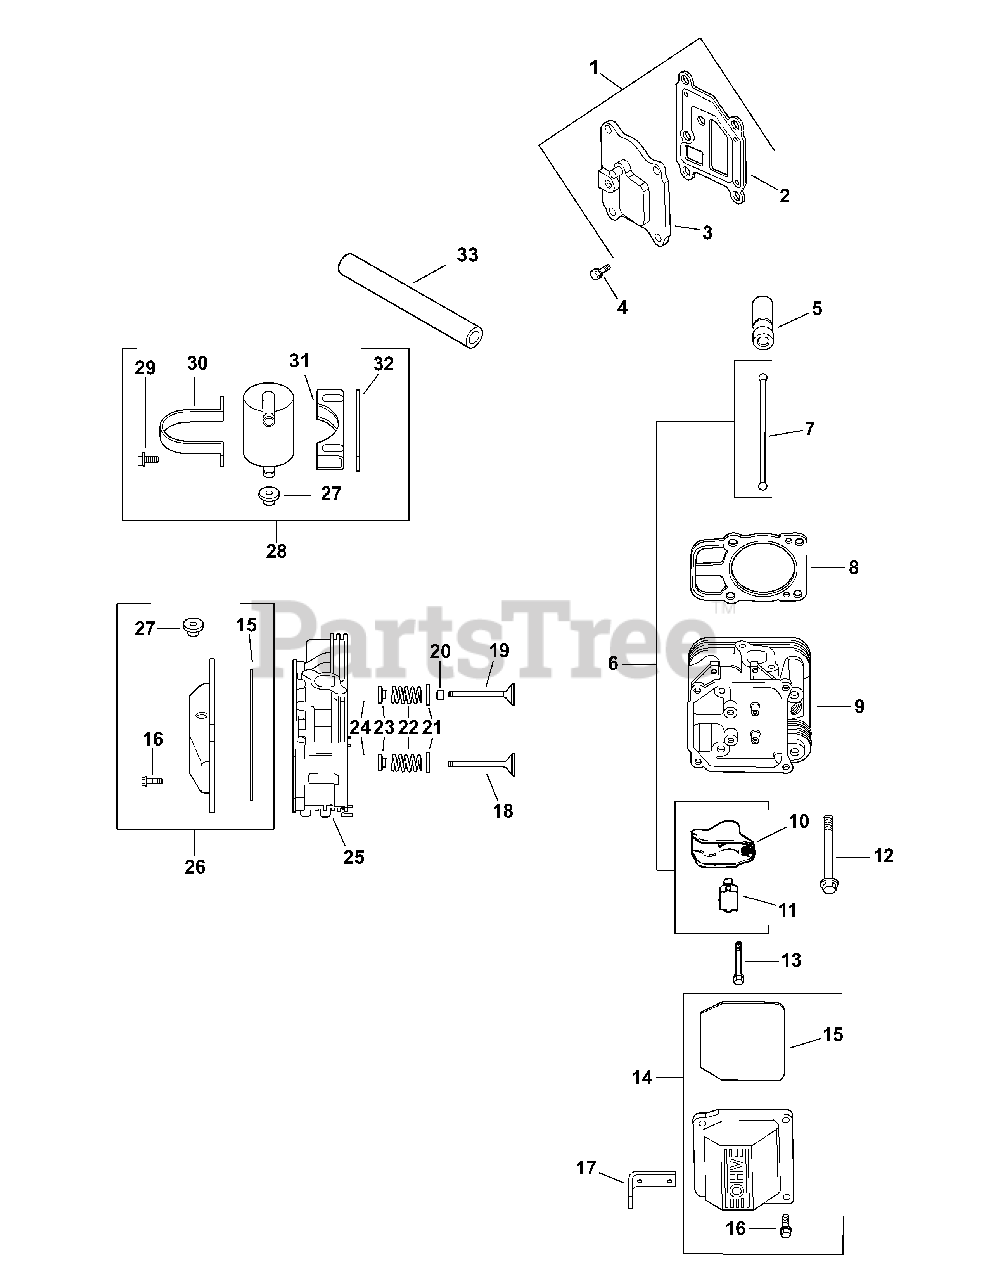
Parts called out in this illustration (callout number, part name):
1	Kit, Breather Cover W/Gasket (Includes 2-3)
2	Gasket, Breather
3	Cover, Breather
4	Screw, Flg Thd Frm M6x1.0x20
5	Kit, Hydraulic Valve Lifter
6	Kit, Valve Train (Includes 7, 10, 11)
8	Kit, Gasket Cylinder Head (Inc. 13 qty. 4)
9	Kit, Head #2 (Includes KH-25-072-04)
11	Pivot, Rocker Arm
12	Screw, Flg M10x1.5x90
13	Screw, Flg M6x1.0x34
14	Kit, Valve Cover-Plain (Includes 15,16)
15	O-Ring, Valve Cover
16	Screw, Flg M6x1.0x30
17	Strap, Lifting
18	Valve, Exhaust (Std)
18	Valve, Exhaust (.25)
19	Valve, Intake (Std)
19	Valve, Intake (.25)
20	Seal, Valve Stem
21	Retainer, Spring
22	Spring, Valve
23	Cap, Valve Spring
24	Kit, Retainer
25	Kit, Head #1 (Includes KH-25-072-04)
26	Kit, Valve Cover Breather (Includes 15, 16, 27)
27	Grommet, Rubber
28	Kit, Breather Seperator (Includes 27)
29	Screw, Flg Thd Frm M5x0.8x16
30	Breather Strap
31	Breather Bracket
33	Hose, Breather
